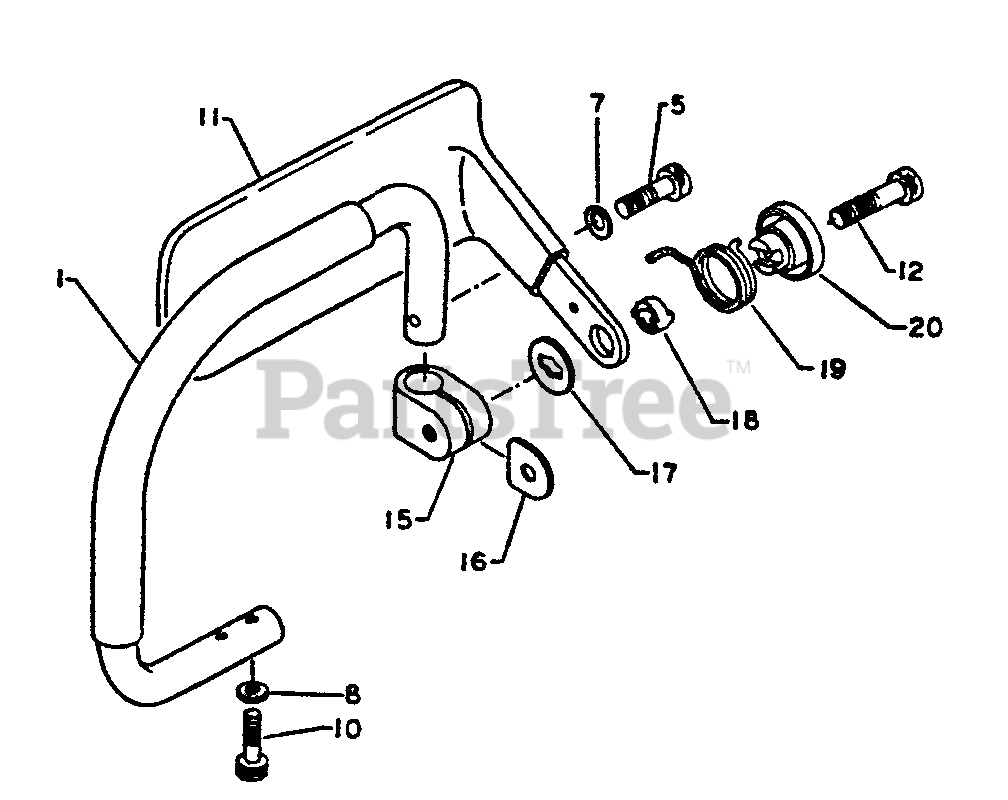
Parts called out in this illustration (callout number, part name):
1	HANDLE, FRONT
5	BOLT 5×20
7	WASHER
8	WASHER 4 MM
10	SCREW - 4×18
10	HAND GUARD ASSY
12	BOLT 5×30
15	HOLDER
17	WASHER
20	RETAINER
